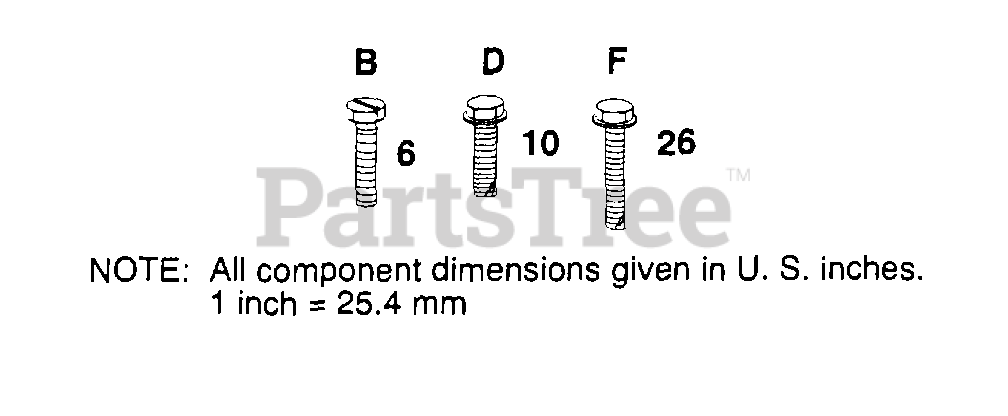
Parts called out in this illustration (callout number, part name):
6	SCREW LT
10	SCREW LT
26	SCREW
